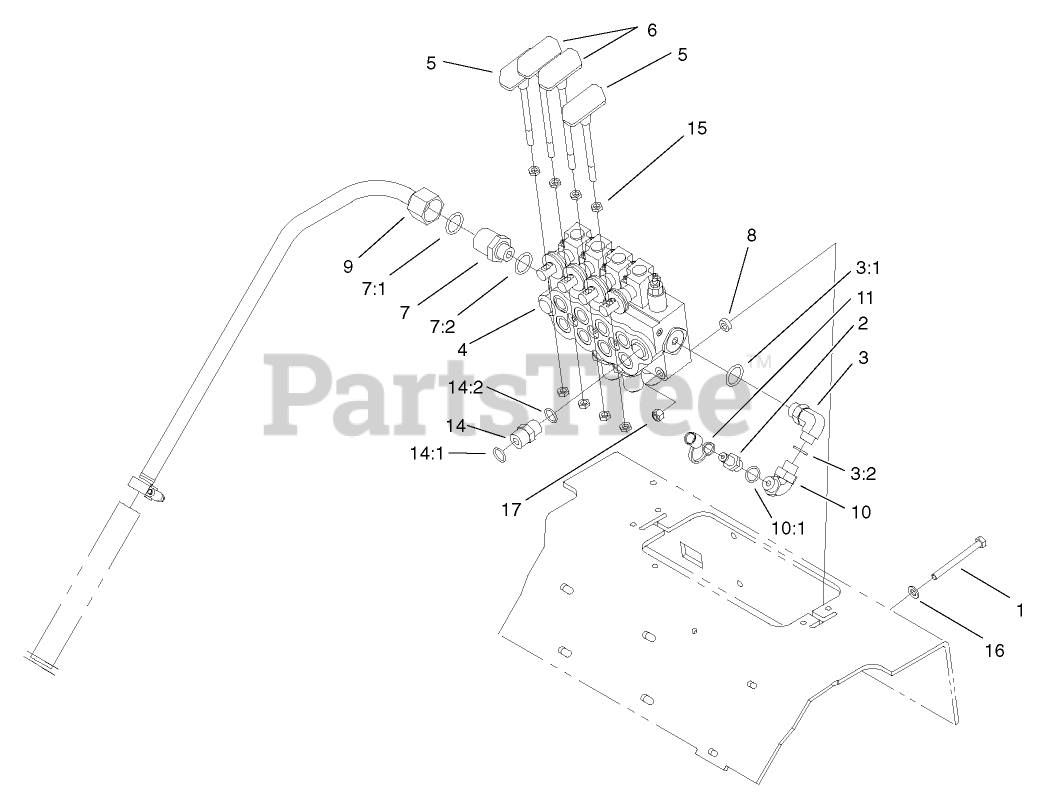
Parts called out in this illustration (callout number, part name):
1	SCREW-HH
2	NIPPLE-TEST
3	FITTING-HYD, 90 DEG
3:1	O-RING
3:2	O-RING
4	VALVE-HYD, 4-SPOOL
5	CYLINDER HANDLE ASM
6	DRIVE HANDLE ASM
7	FITTING-STR
7:1	O-RING
7:2	O-RING
8	SPACER
9	HYD TUBE ASM
10	FITTING-HYD, 90 DEG
10:1	O-RING
11	CAP-DUST
14	FITTING-STRAIGHT
14:1	O-RING
14:2	O-RING
15	NUT-HEX
16	WASHER-PLAIN
17	NUT-LOCK, NI
